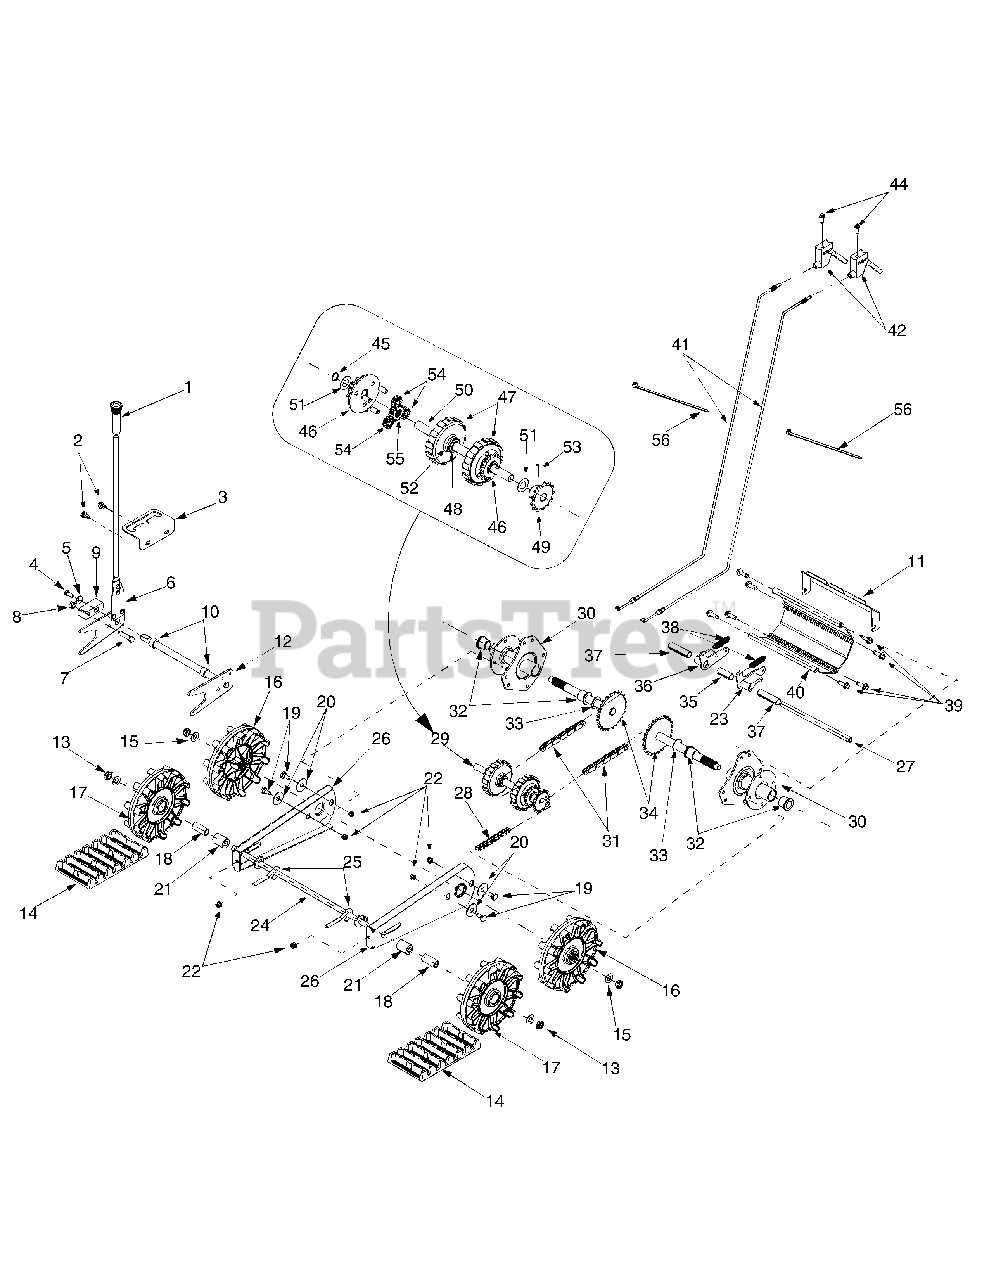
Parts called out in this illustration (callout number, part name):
2	Tap Screw, 5/16-18 x.625
4	Hex Cap Screw, 5/16-24 x.75
5	Bell Washer
7	Hex Cap Screw, 3/8-24 x 1.5
8	Hex Nut, 3/8-24
9	Lift Shaft Drive
13	Jam Nut, 1/2-20
14	Snow Track
15	Flat Washer
16	Track Drive Wheel
17	Track Idler Wheel
19	Screw,.435 x.178-5/16 x.56
20	Flat Washer
22	Flange Lock Nut, 5/16-18
23	LH Dogg Assembly
27	Actuator Shaft
29	Track/Steering Shaft Assembly
32	Flange Bearing
33	Flat Washer
34	Axle Assembly
36	RH Dogg Assembly
37	Spacer
38	Extension Spring
39	Tap Screw, 5/16-18 x 1
40	Track Housing
41	Steering Cable
42	Steering Trigger
44	Screw, #10-24 x 1.375
45	Retaining Ring
46	Carrier Assembly
48	Retaining Ring
49	13-Tooth Sprocket
50	Track Steering Drive Shaft
51	Flat Washer
52	Flat Washer
53	Spiral Pin
54	12-Tooth Gear
55	18-Tooth Gear
56	Cable Tie
